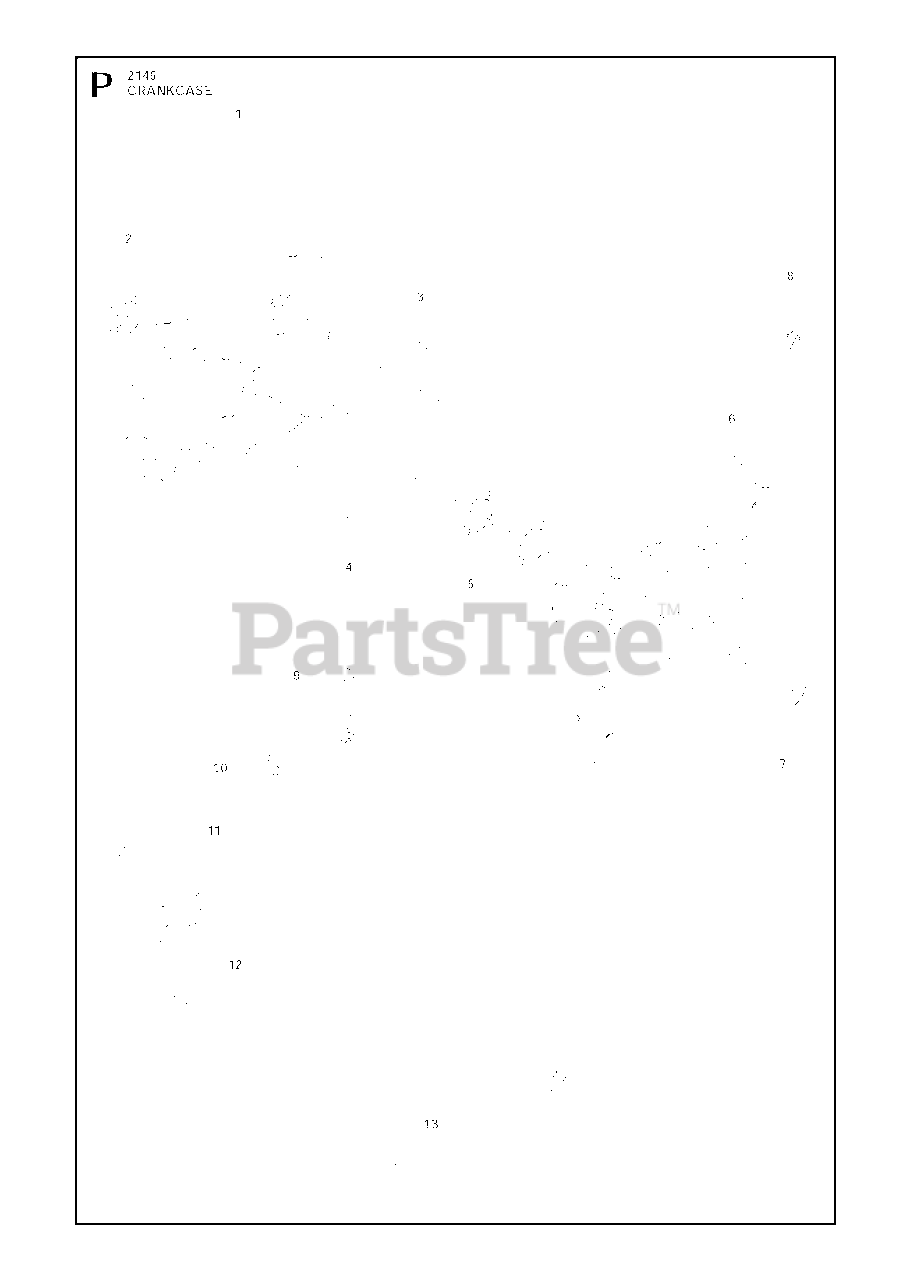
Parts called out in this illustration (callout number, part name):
1	CRANKCASE
2	SEALING RING
3	PIN 5X14
4	GASKET
5	BALL BEARING-6202-C3 SKF
6	SCREW MC6S 5X20
7	SEAL RING
8	CABLE SOCKET
9	FUEL TANK BUSHING
11	SEAL
12	AIR CONDUCTOR
13	SHORTING LEAD
